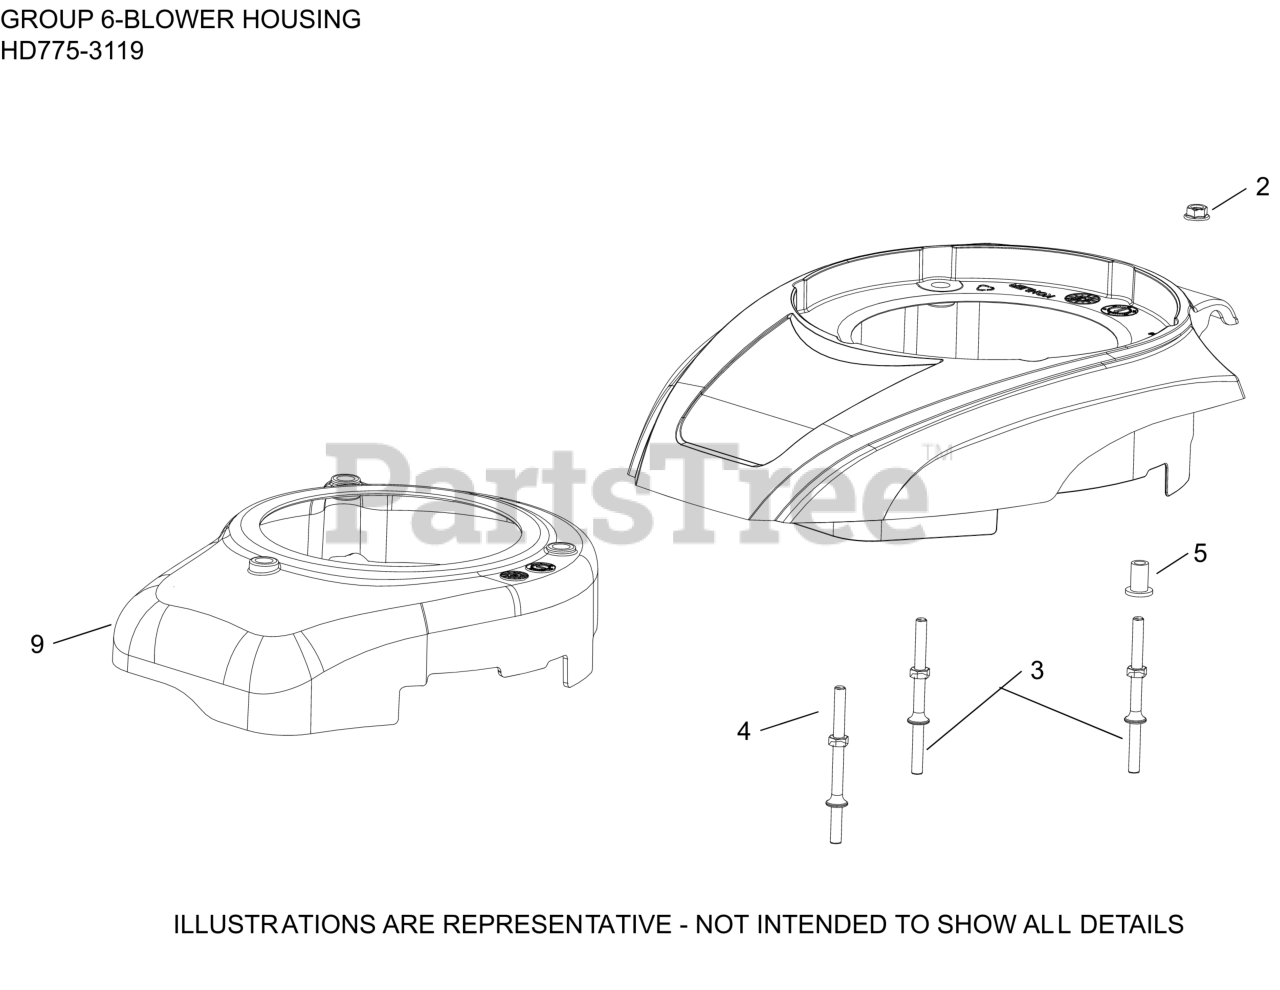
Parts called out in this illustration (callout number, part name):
2	NUT, LOCK M6
3	STUD-USE 14 072 25-S
4	STUD-USE 14 072 26-S
9	HOUSING, BLOWER
